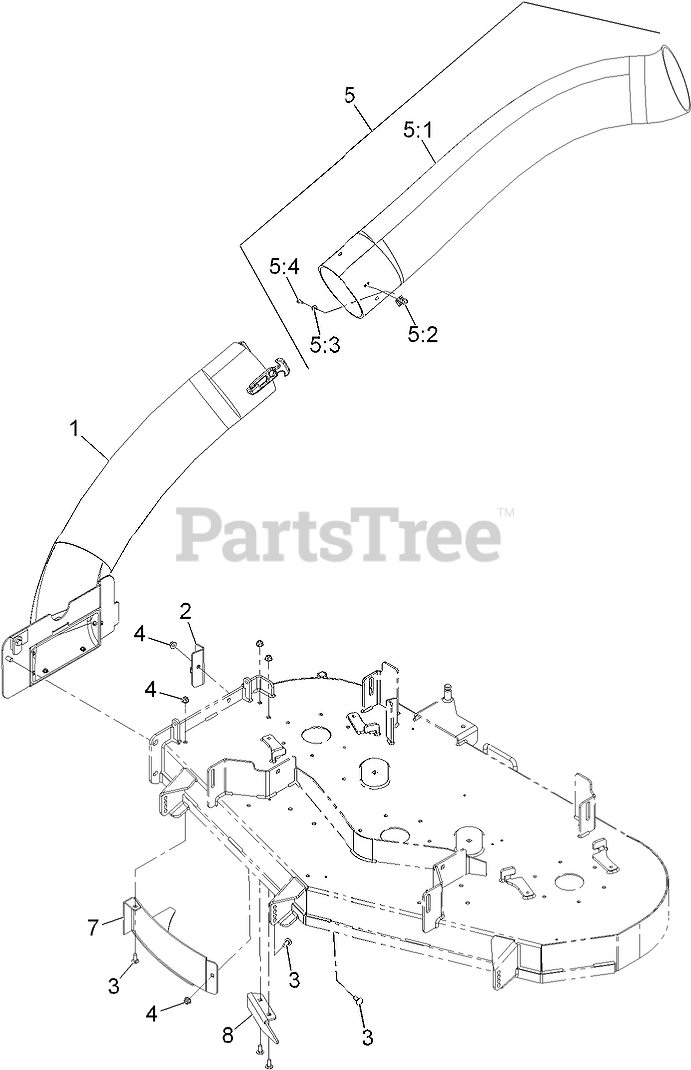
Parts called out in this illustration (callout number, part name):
1	TUBE AND FRAME ASM
2	BRACKET-BOOT MOUNT, 52 IN
2	BRACKET-BOOT MOUNT, 48 IN
3	SCREW-CARR
4	NUT-HF, NI
5	UPPER TUBE W/KEEPER ASM
5:1	TUBE-UPPER
5:2	LATCH-KEEPER
5:3	WASHER-FLAT
5:4	SCREW-PPH
7	WLD,DISCHARGE BAFFLE
8	BAFFLE-DISCHARGE
